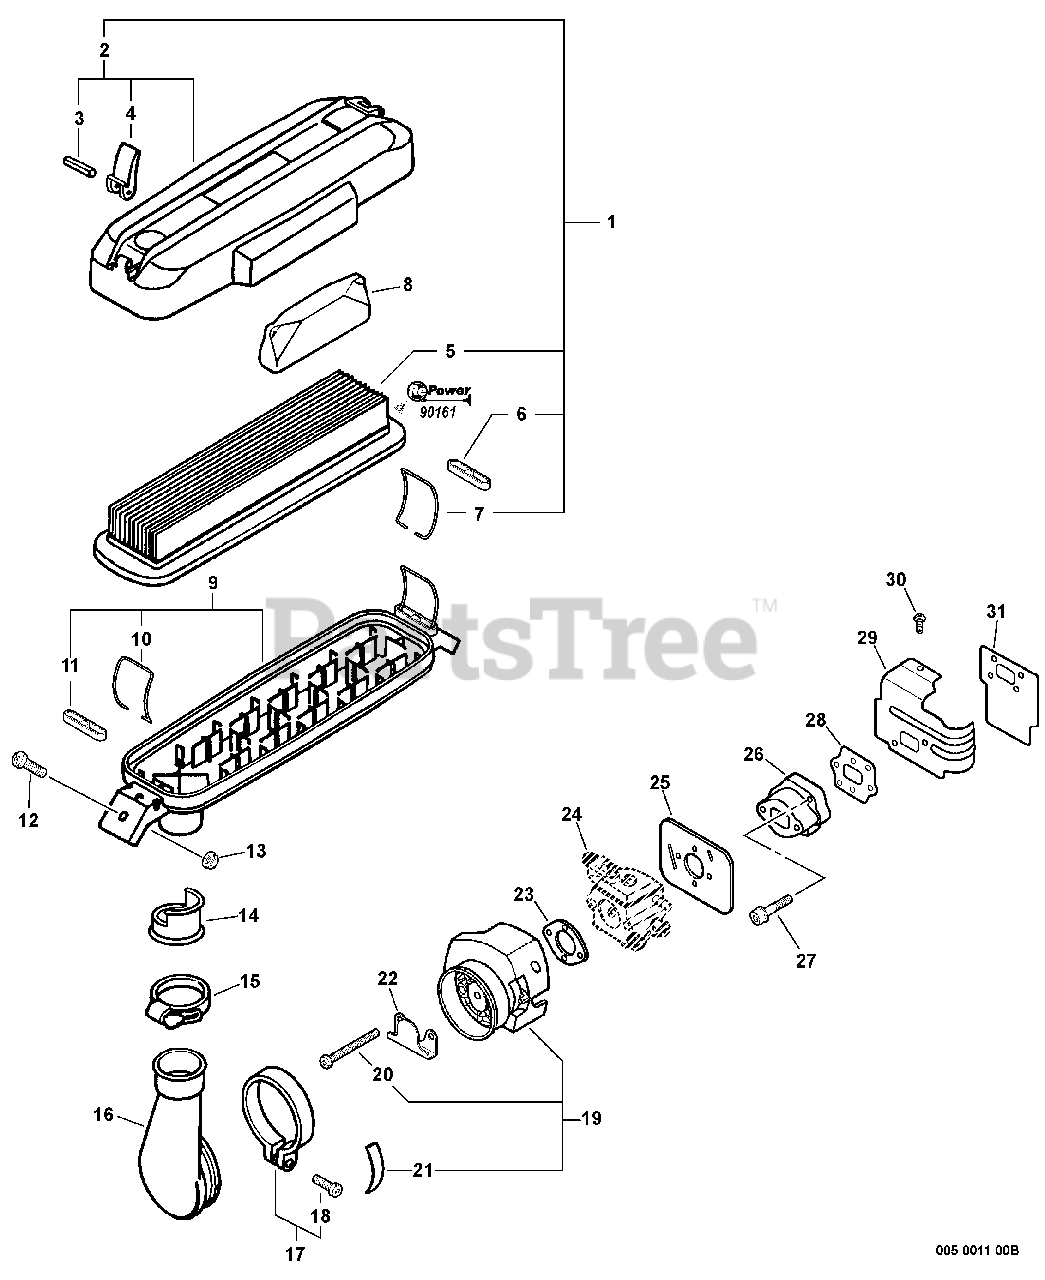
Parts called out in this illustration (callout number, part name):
1	AIR FILTER KIT
2	AIR FILTER COVER ASSY
3	PIN - SPRING -- 3X25
5	FILTER, AIR
6	RETAINER
7	RING, RETAINING
8	SILENCER
9	AIR FILTER CASE ASSY
10	RING, RETAINING
11	RETAINER
12	SCREW - 5X14
13	NUT - 5 -- FLANGE
15	CLAMP, HOSE
16	ADAPTOR, INTAKE
17	CLAMP KIT
18	SCREW - 5X25
19	BRACKET KIT - PLASTIC
20	SCREW - 5X57
21	LABEL - CHOKE
22	PLATE, PREVENT
23	GASKET, INTAKE
24	CARBURETOR
25	GASKET, INTAKE
26	INSULATOR, INTAKE
27	SCREW - 5X25
28	GASKET, INTAKE
29	COVER, CYLINDER - INTAKE
30	SCREW - 5X10
31	SHIELD, INTAKE
32	RePower TUNE-UP KIT
